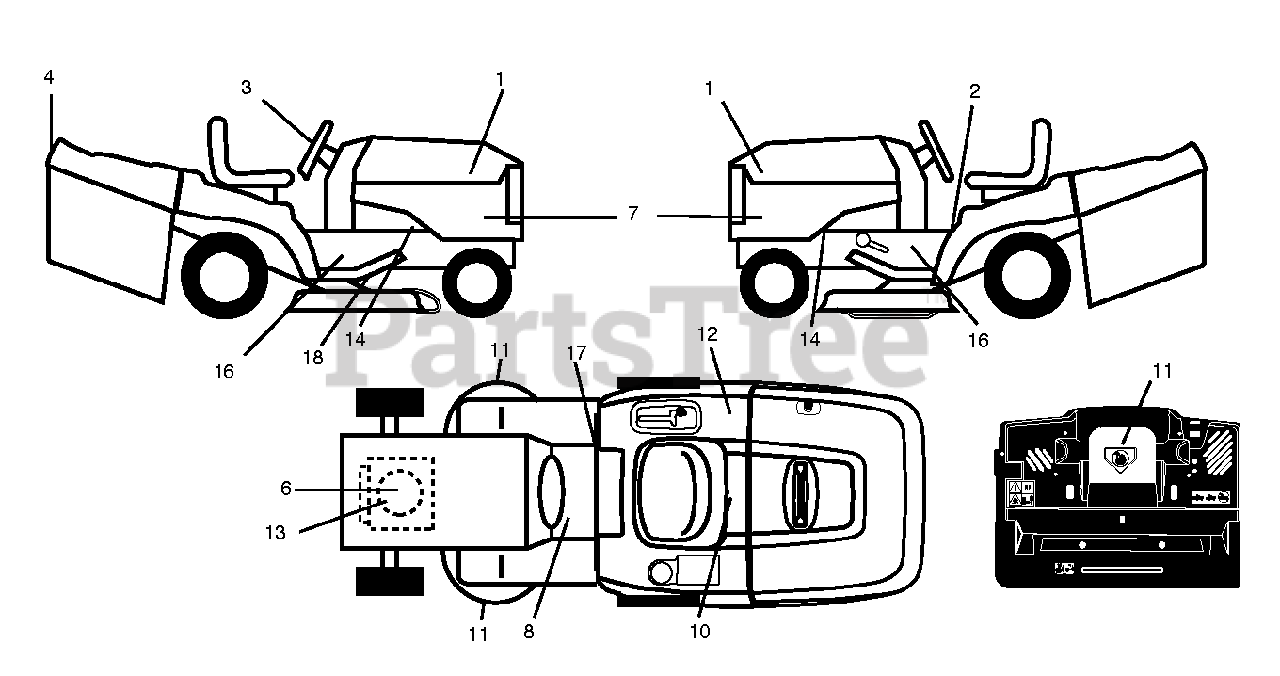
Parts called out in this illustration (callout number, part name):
10	DECAL BTRY SYMBOLS
11	DECAL.INTERNATIONL.CUTFINGER
12	Decal, 100 DB/CE
16	DECAL.CHAS.TURBO
17	DECAL PARK BRAKE
